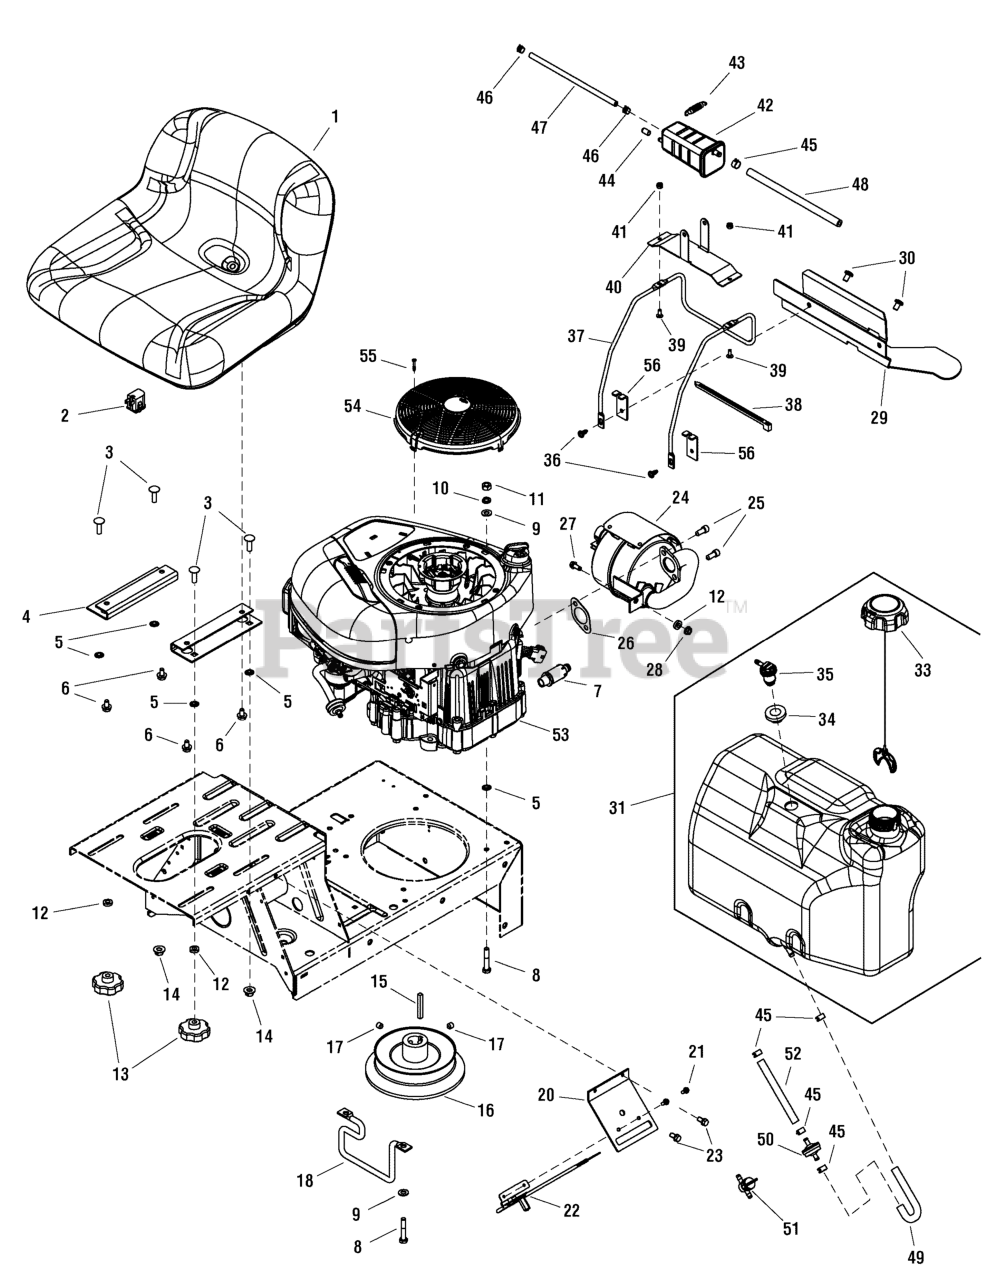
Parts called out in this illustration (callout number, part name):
1	SEAT, 11.58"
2	SWITCH, Seat, Push Button (NC)
3	BOLT, 5/16-18 x 1" Square Neck Carriage, GR 5 YZ
4	PLATE, Seat Adapter
5	RETAINER, 5/16" Bolt
6	BOLT, 5/16-18 x 1/2" Hex Flange Nyloc
7	OIL VALVE ASSEMBLY
8	SCREW, 5/16-24 x 1-3/4" Hex Head Cap, GR 5
9	WASHER, 11/32" Flat
10	WASHER, .32 x .58 x .08 Split Lock
11	NUT, 5/16-24 Hex, GR 5
12	SPACER, .33 x .63 x .156
13	KNOB, Fluted, 5/16-18
14	NUT, 5/16-18 Large Flange Center lock
15	KEY, 1/4" Square x 2" Long
16	WELDMENT, 5.75" O.D. Drive Disc
17	SET SCREW, HRSS, 3/8-16 x 3/8"
18	BELT GUIDE, 28" (5.74" Bolt Pattern, 4.74" Belt Gap)
20	PLATE, Throttle
21	SCREW, #10-24 x 1/2" Hex Washer Self-Tap (Torx)
22	CONTROL, Throttle (23.6" long) (Briggs Engines)
23	SCREW, 1/4-20 x 1/2" Hex Washer Self-Tap
24	MUFFLER, w/Heat Shield (Briggs 11 thru 17HP)
25	SET SCREW, 5/16-18 x 3/4" Socket Head, GR8
26	GASKET, Exhaust
27	SCREW, 1/4-20 x 5/8" Hex Washer Head Self-Tap
28	NUT, 1/4-20 Hex Flange Lock
29	BRACKET, Mounting Tank, RER
30	SCREW, 5/16-18 x 1/2" Pan Head Self-Tap (Torx #T-40)
31	ASSEMBLY, Fuel Tank, Fluorinated, RER
33	CAP ASSEMBLY, Ratchet, Non Vented-w/Tether
34	GROMMET
35	ASSEMBLY, Remote Vent, No Valve
36	SCREW, 1/4-20 x .550" Pan Head Self-Tap Torx
37	HOLDER, Fuel Tank, RER
38	CABLE TIE, 7"
39	BOLT, #10-24 x 1/2" Flat Head Square Neck, YZ
40	BRACKET, Carbon Canister
41	NUT, #10-24 Hex Nyloc
42	CANISTER, Carbon 140CC - RER
43	SPRING, Tension
44	CAP, Vinyl
45	CLAMP, .490 x .31
46	CLAMP, Hose - CTL
47	HOSE, Vapor, 5MM ID x 9 MM OD x 8.5"
48	HOSE, Fuel, Low Perm, 1/4" ID x 9"
49	HOSE, Fuel
50	FILTER, Fuel (In-Line)
51	VALVE, Fuel Shut-Off (Accessory)
52	HOSE, Fuel, 5" long
53	* ENGINE, 12.5HP, B&S W/ OIL FILTER, RER
54	COVER, Static
56	BRACKET, Tank Brace
